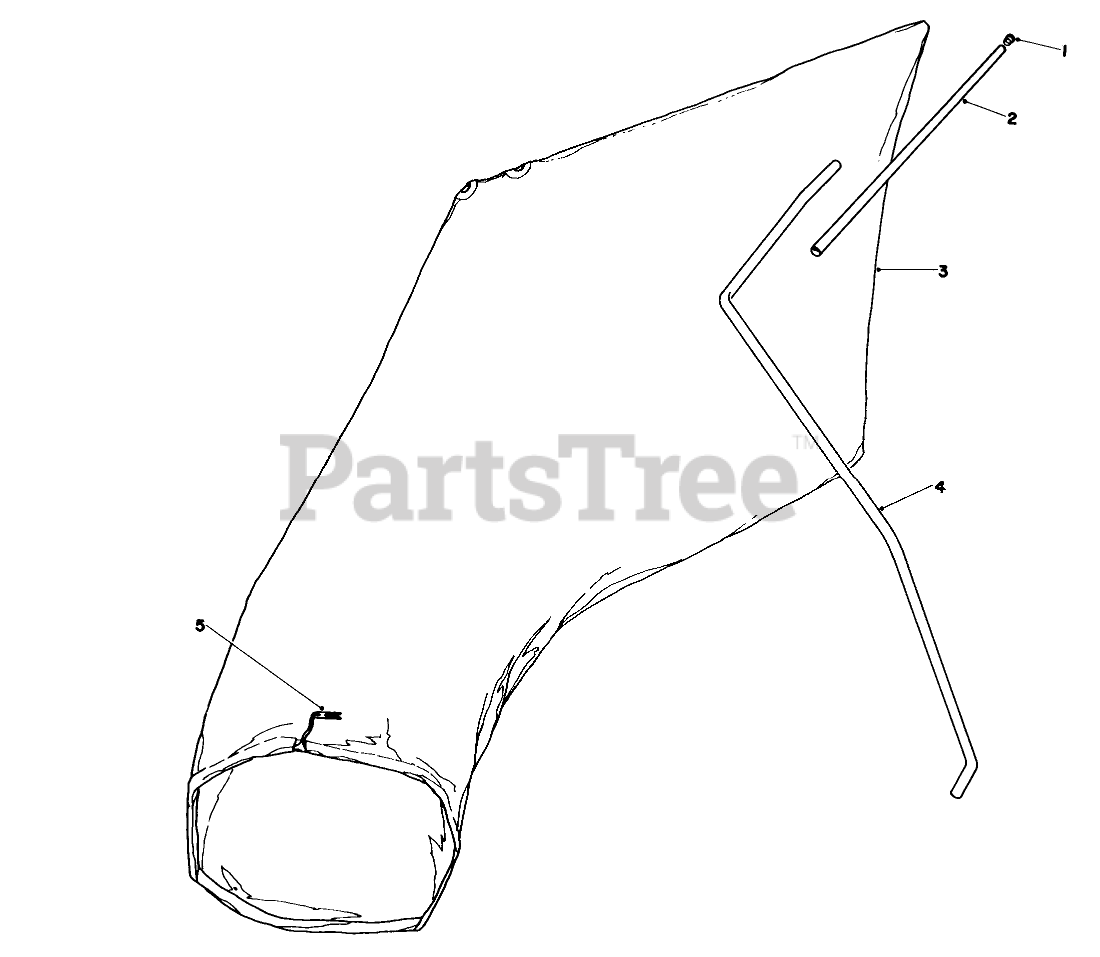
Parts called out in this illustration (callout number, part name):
2	BAG HANGER TUBE
3	Bag (Incl. Ret. #5)
4	HANGER ROD
5	BAG CORD FASTENER
